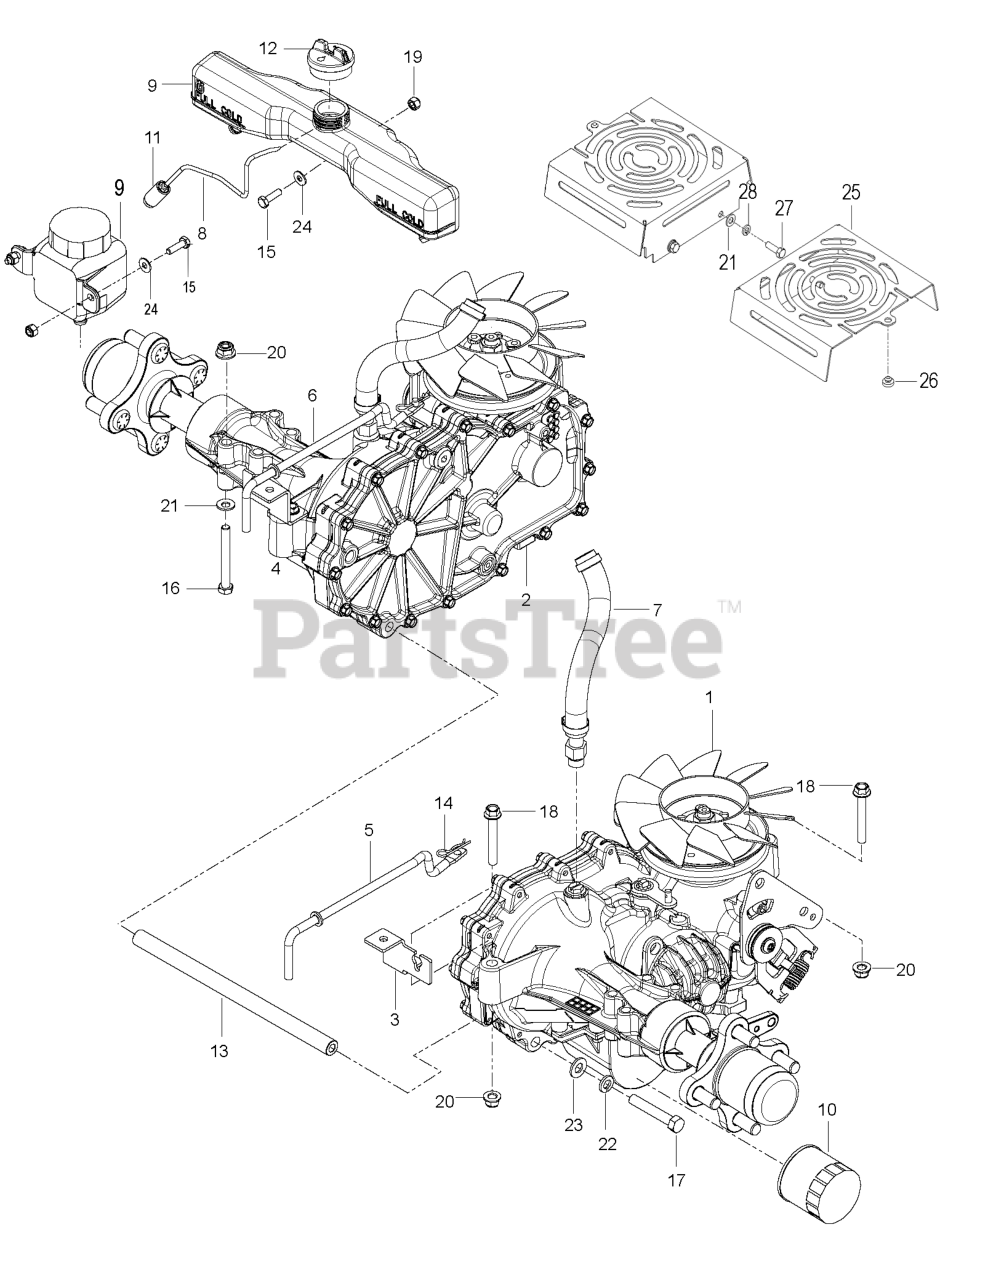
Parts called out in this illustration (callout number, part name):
1	HG_TRANS ZT-3100 LT
2	HG_TRANS ZT-3100 RT
3	BRACKET.TRANS.LT.BLACK
4	BRACKET, TRANS, RT BLACK
5	LINKAGE, LEFT BYPASS
6	LINKAGE, RIGHT BYPASS
7	HOSE ASSY, EXPANSION
9	TANK EXPANSION W/CAP
9	TANK.EXPANSION.350ML 71328
10	HG_FILTER, ZT4800 52114
11	FUEL PICK-UP ASSY
12	CAP EXPANSION W/SEAL
13	TUBE, SPACER, 3400
14	HAIRPIN #2
15	HCS 1/4-20X7/8 GR5
16	HCS 5/16C X 2-3/4
16	BOLT HEX
17	HCS 3/8-16X2-1/4 LOC PATCH GR8
18	HHFS 5/16-18 X 2.25 GD 5
19	NUT.1/4-20.HEX.NYLOC.ZD
20	5/16-18 NYLOC FLANGE NUT
21	WASHER
22	SLW 3/8 STD
23	WASHER 3/8 SAE FLAT
24	WASHER 1/4 SAE
25	SHIELD FAN BLACK
26	GROMMET, BUMPER
27	BOLT.FIN.HEX.5/16-18UNC X 1.00
27	HCS 5/16C X 1
28	WASHER.LOCK.HVY.HLCL.SPR.5/16
